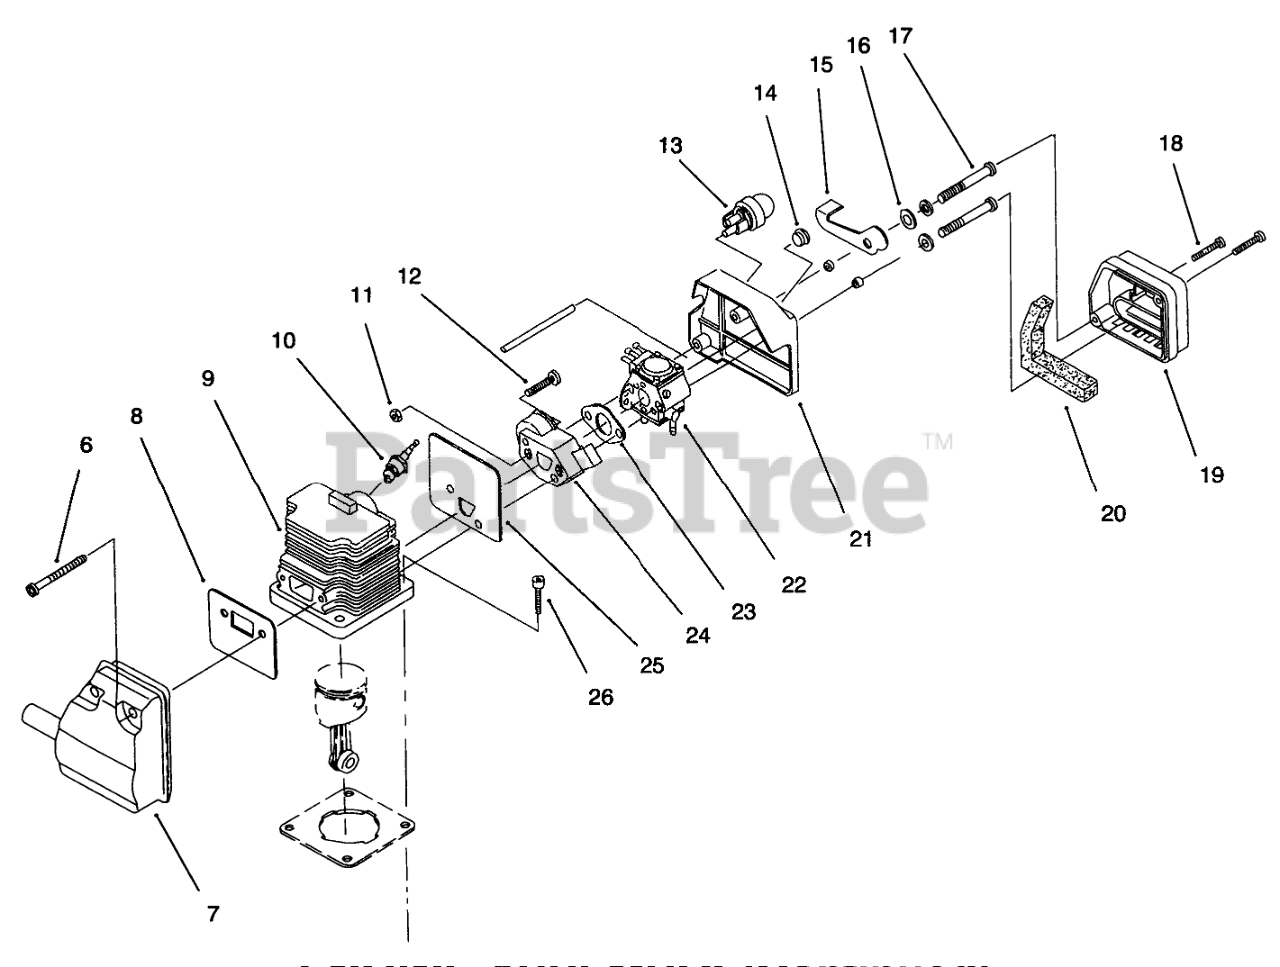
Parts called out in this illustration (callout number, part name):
6	MUFFLER MOUNTING SCREWS
7	MUFFLER ASSEMBLY
8	MUFFLER GASKET
9	CYLINDER
10	SPARK PLUG
11	SPACER NUT SET
12	SPACER SCREW SET
13	PRIMER & HOSE ASM
14	SWITCH PLUG
15	CHOKE LEVER
16	WAVEY WASHER
17	CARB MOUNTING ASM
18	Screw
19	AIR CLEANER COVER
20	FOAM AIR FILTER ELEMENT
21	Air Cleaner Base Asm.
22	ASM - CARBURETOR
23	CARB.GASKET(PK.10=1)
24	CARBURETOR SPACER ASM
25	CYL/CARB SPACER GASKET
26	SCREW
